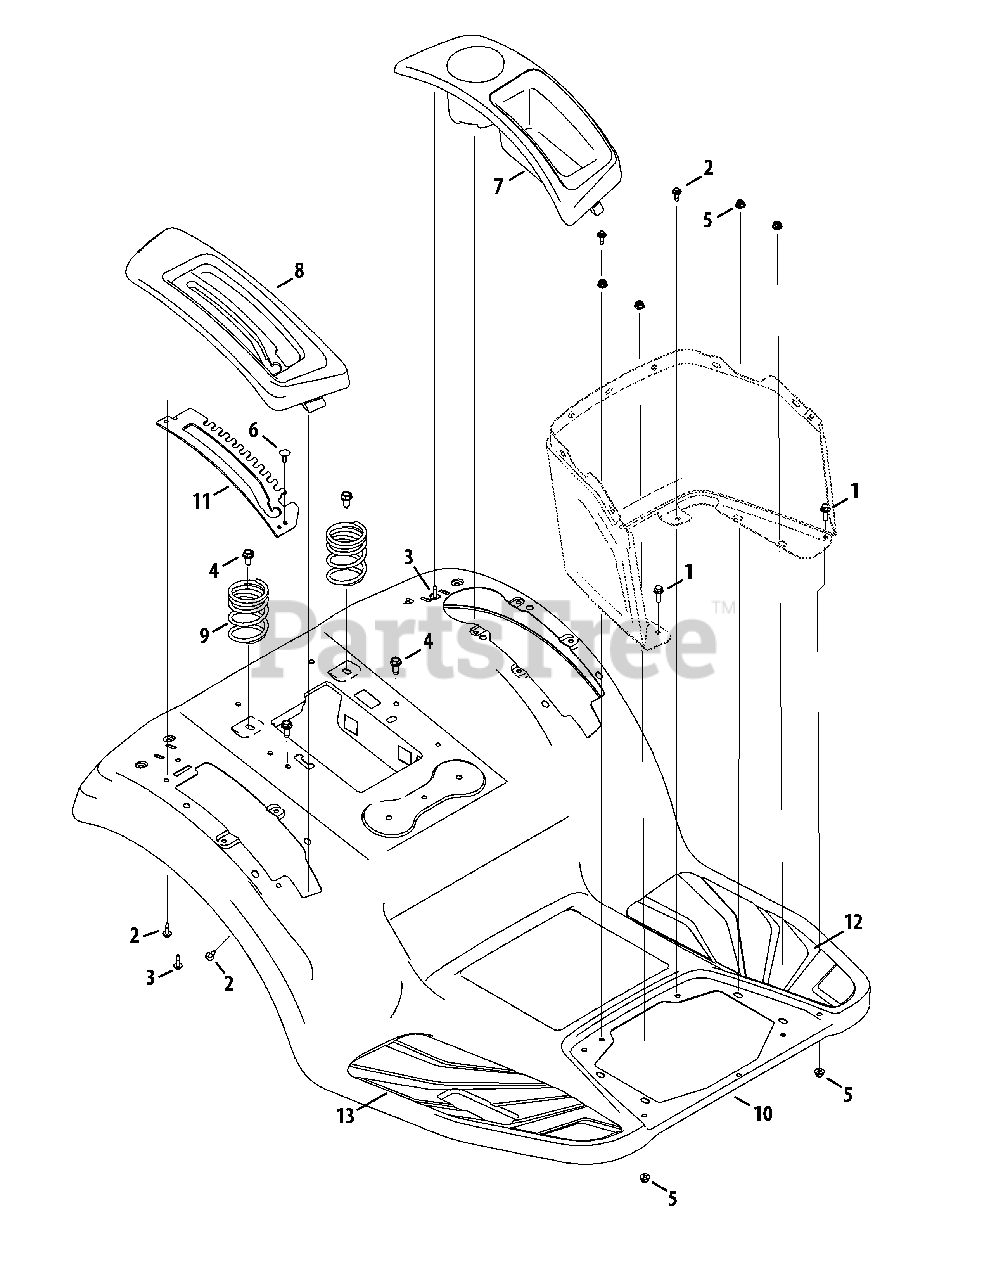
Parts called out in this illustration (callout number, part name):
1	Hex flange Screw, 1/4-20 x .75
2	Screw, M6-1 x .625
3	Screw, 1/4-10 x .75
4	Screw, Self-tapping, 5/16-18, 0.750,
5	Nut, Flange Lock, 1/4-20, Nylon
6	Ratchet Clip, .250 DIA
7	Cover, LH
8	Cover, RH, Manual PTO
9	Compression Spring, 2.50 x 3.951 x .207
10	Fender
12	Pad, Foot, LH
13	Pad, Foot, RH
